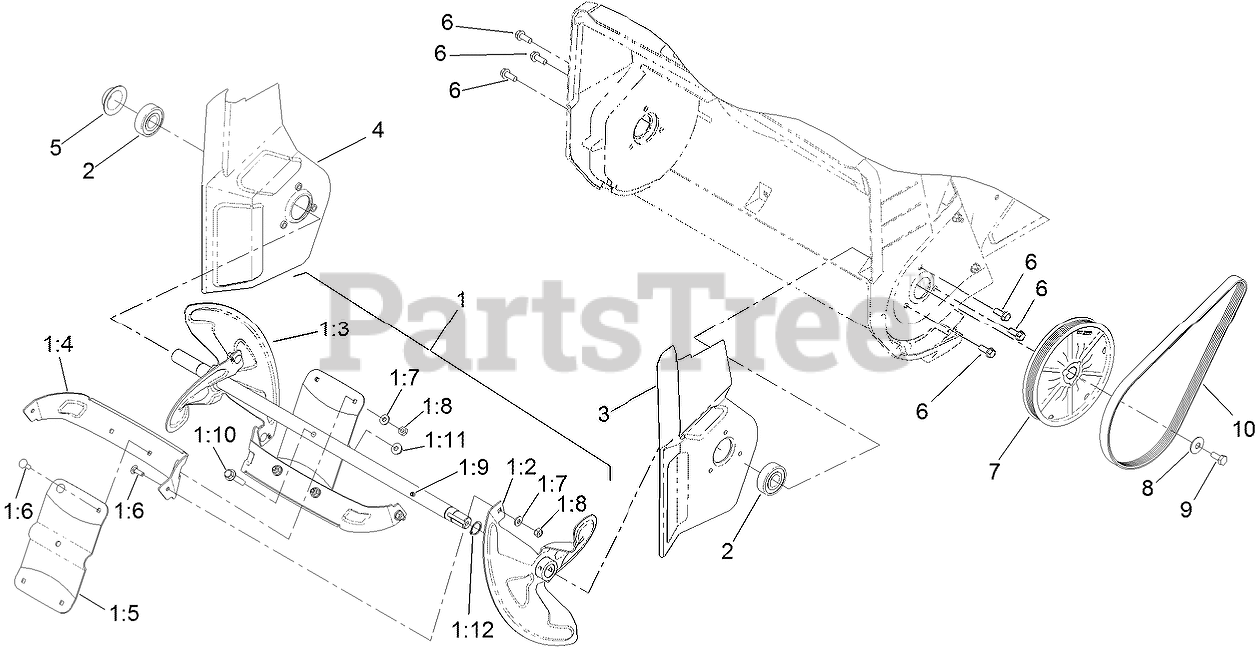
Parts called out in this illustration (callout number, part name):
1	ROTOR ASM
1:2	BLADE-ROTOR, LH
1:3	BLADE-ROTOR, RH
1:4	ROTOR-CENTER
1:5	PADDLE-CENTER
1:6	SCREW-CARR
1:7	WASHER-FLAT
1:8	NUT-LOCK, NI
1:9	PIN-SPIRAL
1:10	SCREW-HHF
1:11	NUT-HF
1:12	RING-SNAP, EXTERNAL
2	BEARING-BALL
3	EXTENSION-LH
4	EXTENSION-RH
5	CAP-SIDEPLATE, RH
6	SCREW-HWH
7	ROTOR PULLEY ASM (6 GROOVE)
8	WASHER-BELLEVILLE
9	SCREW-HH
10	BELT-V, RIBBED
